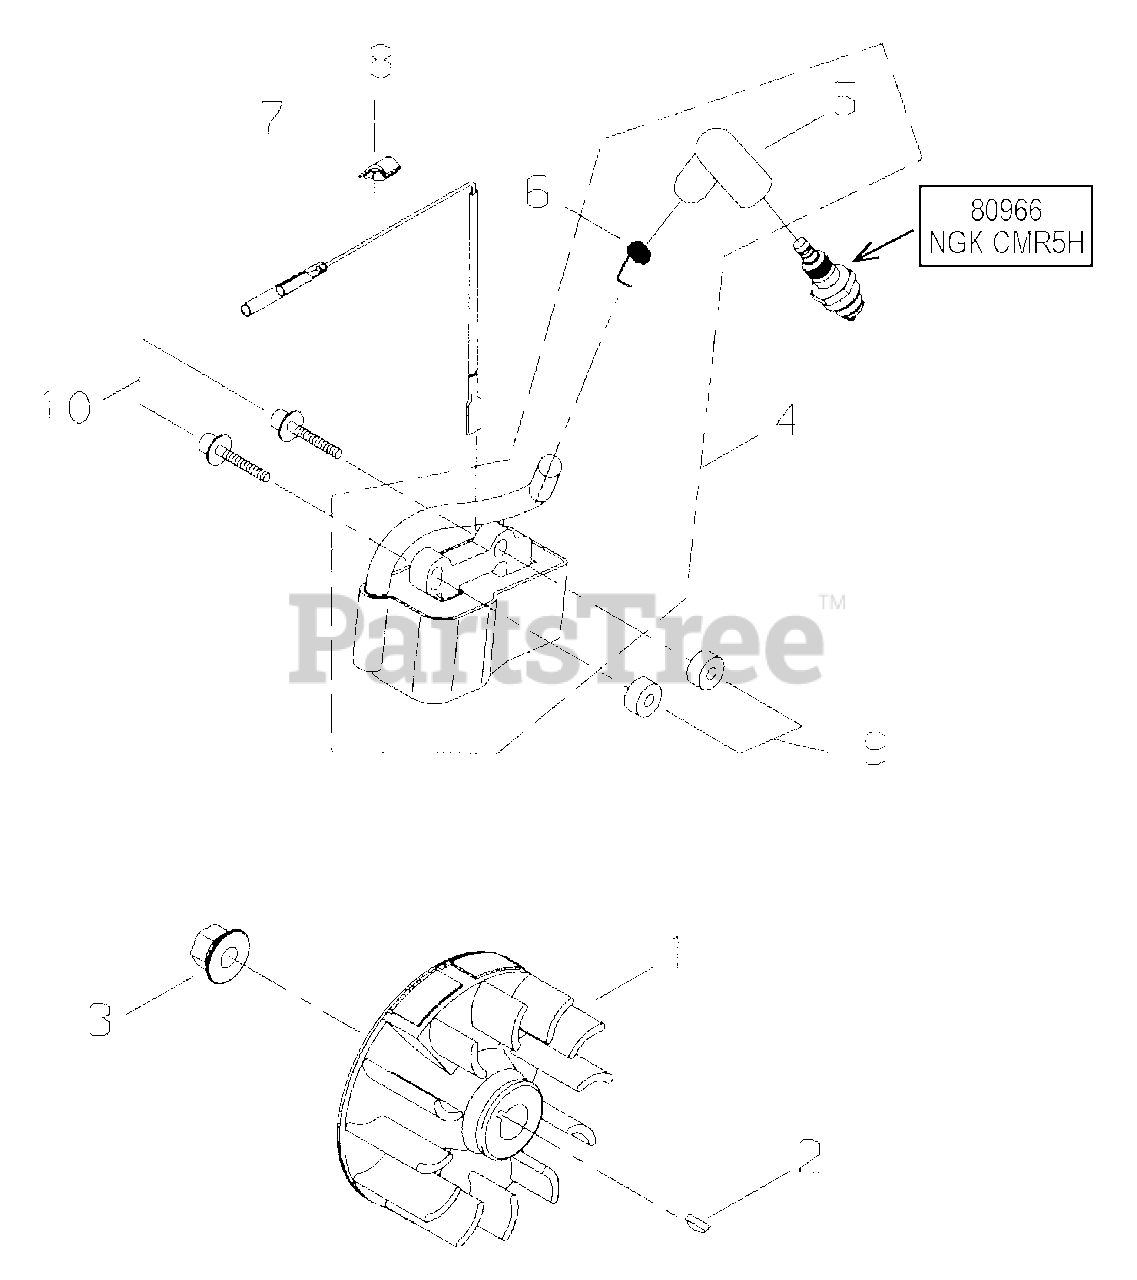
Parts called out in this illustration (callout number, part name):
1	FLYWHEEL
2	KEY, WOODRUFF 3×10
3	NUT M8
4	COIL ASSY, IGNITION
5	CAP, SPARK PLUG
6	TERMINAL, SPARK PLUG
7	LEAD - IGNITION
8	GROMMET, LEAD
9	INSULATOR 4.2×11×6
10	BOLT M4×26
